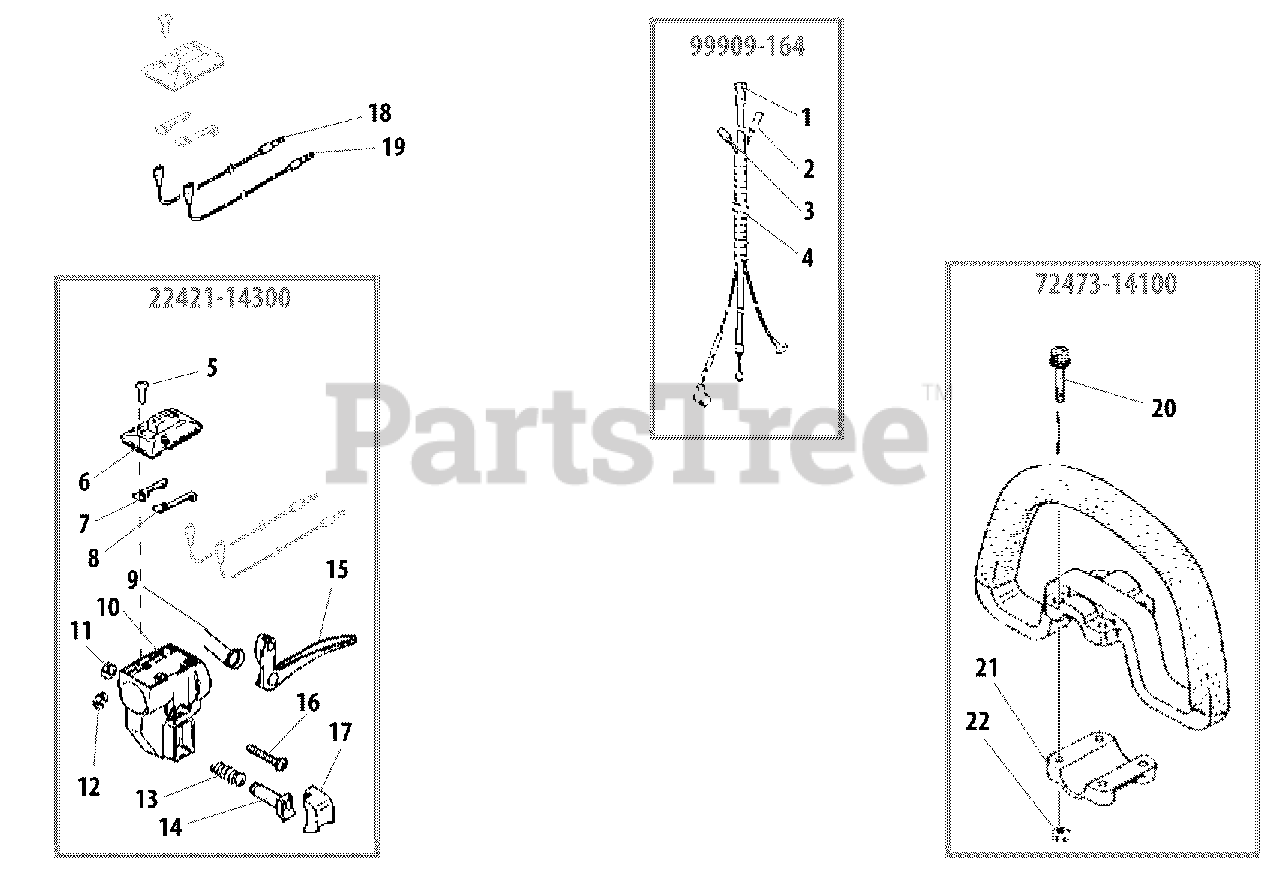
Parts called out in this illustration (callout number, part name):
1	CABLE, THROTTLE
2	LEAD - GROUND
3	LEAD - IGNITION
4	TUBE, PLASTIC PROTECTIVE
5	SCREW, TAPPING
6	SWITCH, ON-OFF
7	PLATE, RIGHT GROUND
8	PLATE, LEFT GROUND
9	SPRING, RETURN
10	BODY, THROTTLE
11	NUT, NYLON
12	RING, SNAP
13	SPRING
14	LOCKOUT, THROTTLE
15	TRIGGER, THROTTLE
16	SCREW
17	BUTTON, THROTTLE LOCK
18	WIRE, RIGHT LEAD
19	WIRE, LEFT LEAD
21	BRACKET, MOUNTING
22	NUT M5
A	CONTROL CABLE ASSY
A	THROTTLE CONTROL ASSY
A	HANDLE ASSY, FRONT
